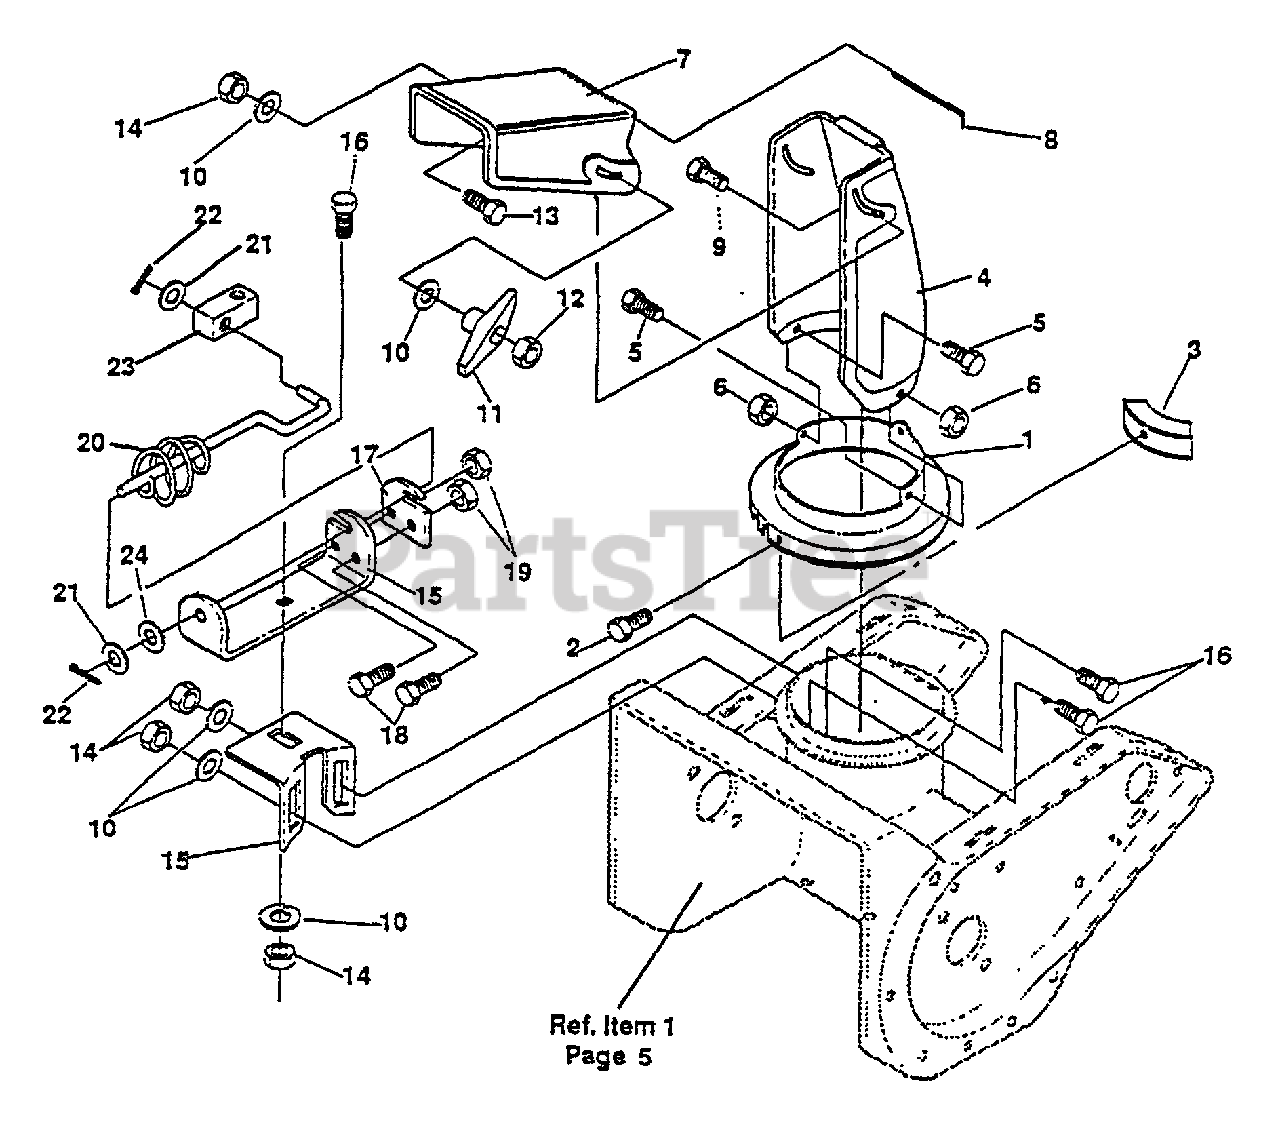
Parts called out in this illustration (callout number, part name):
1	RING, LWR CHUTE
2	SCREW - 1/4-14 X 5/8"
3	CLIP, CHUTE RING PLASTIC
4	CHUTE - LOWER
5	SCREW - 1/4-20 X .50"
6	NUT - 1/4-20
7	CHUTE - UPPER
8	WIRE, CHUTE HINGE
9	BOLT - 5/16-18 X 1.25"
10	WASHER
11	KNOB, T 2 BLADE W/5/16-18 NUT
12	NUT - 5/16-18
13	SCREW - 5/16-18 X 3/4"
14	NUT - 5/16-18
15	BRACKET, WORM ADJUST
15	BRACKET, CHUTE ROD
16	BOLT - 5/16-18 X 3/4"
17	PLATE, CHUTE ROD
18	SCREW - 1/4-20 X .50"
19	NUT - 1/4-20
20	CHUTE CONTROL ROD ASSY - LOWER
21	WASHER - .390 X .75 X .031
22	PIN, SPLIT
23	BLOCK, PIVOT PLASTIC
24	WASHER - WAVE
